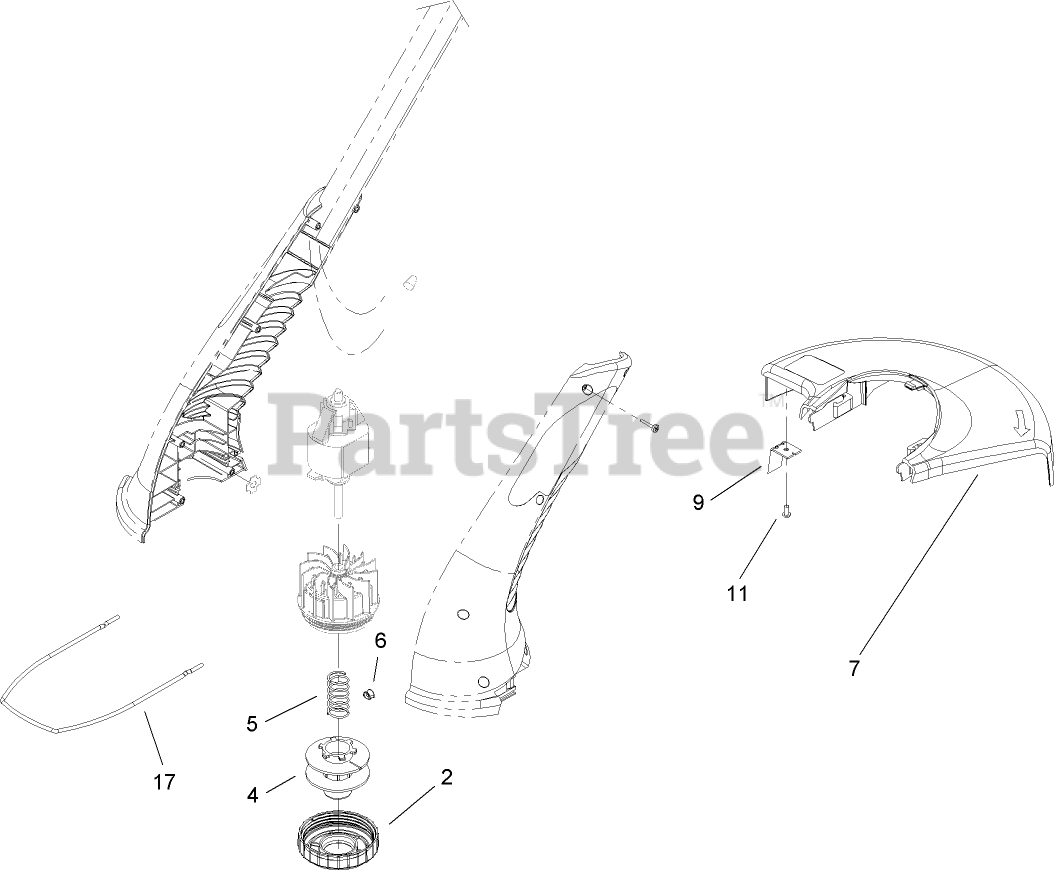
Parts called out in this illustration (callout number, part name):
2	CAP-DRUM
4	.065 SPOOL ASM
4:1	SPOOL-LARGE
5	SPRING-EXTENSION
6	EYELET-GUIDE
7	SHIELD-12 INCH
9	BLADE-CUTOFF
11	SCREW-PPH
